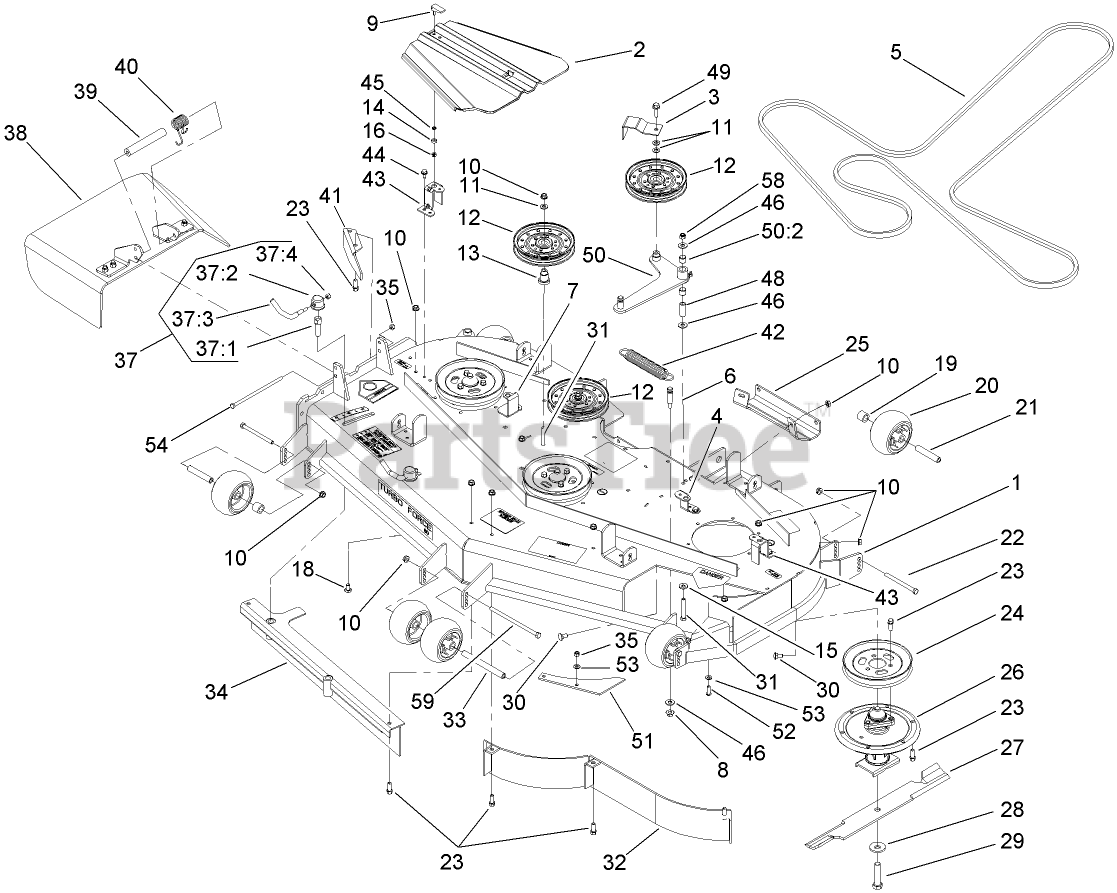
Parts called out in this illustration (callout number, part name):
1	DECK DECAL ASM
2	COVER-BELT
3	GUIDE-BELT
4	BRACKET-COVER, TALL
5	BELT-V
6	PIN-THREADED, SPRING ANCHOR
7	BRACKET-COVER
8	NUT-HF
9	HANDLE-LATCH, SWELL
10	NUT-HHF, WHIZ
11	WASHER-FLAT
12	Idler-Flat
13	MOUNT-PULLEY
14	BUSHING-LATCH, SWELL
15	WASHER-BELLEVILLE
16	NUT-LOCK, HH
18	SCREW-CARR
19	TUBE-SPACER
20	ROLLER-SCALP, ANTI
21	TUBE-SPANNER
22	SCREW-HH
23	SCREW-HWH
24	Pulley
25	Plate-Skid
26	SPINDLE ASM
27	BLADE-HI FLOW
28	Washer-Blade Bolt, Heavy
29	Screw-Cap
30	SCREW-CARR
31	SCREW-HH
33	SPACER-WHEEL
35	NUT-LOCK, NI
37	LEVER ASM
37:1	Screw-Lock
37:2	CAP-LOCK
37:3	Lever-Lock
37:4	NUT-LOCK, NI
38	RUBBER DEFLECTOR ASM
39	SPACER
40	SPRING-TORSION
41	BAFFLE-DISCHARGE
42	SPRING-EXTENSION
43	BRACKET-COVER
44	SCREW-HWHTF
45	WASHER
46	WASHER-FLAT
48	BUSHING
49	SCREW-HHF
50	DECK IDLER ARM ASM
50:2	SLEEVE-BEARING
51	PLATE-TURBO
52	SCREW-HSBH
53	WASHER-SPRING
54	SCREW-HH
58	NUT-LOCK, NI
59	SCREW-HH
